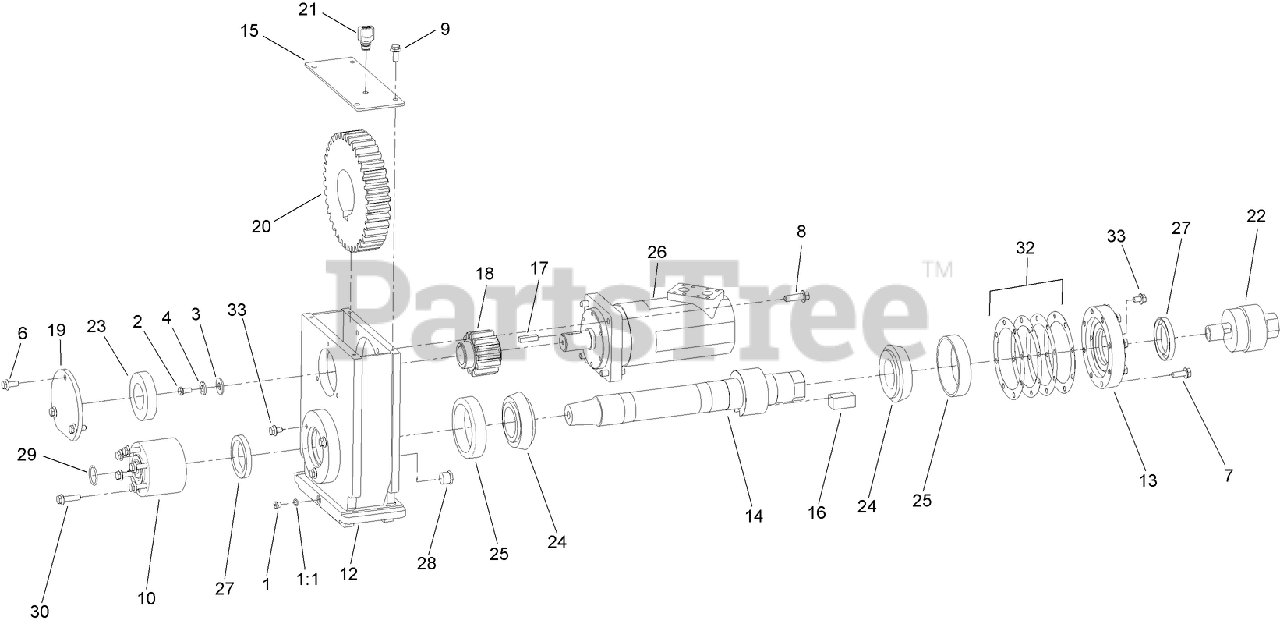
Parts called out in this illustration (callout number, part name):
1	PLUG ASM
1:1	O-RING
2	SCREW-HH
3	WASHER-FLAT
4	WASHER-FLAT
6	SCREW-HHF
7	SCREW-HHF
8	SCREW-HHF
9	SCREW-HHF
10	ADAPTER-SPINDLE
12	BOX-ROTARY
13	PLATE-BEARING CAP
14	SPINDLE-ROTARY
15	ROTARY BOX COVER BLACK]
16	KEY-ROTARY BOX
17	KEY-BOX, ROTARY
18	GEAR-PINION, ROTARY BOX (13T)
19	PLATE-RETAINING, ROTARY BOX
20	GEAR-RING, ROTARY BOX (38T)
21	BREATHER
22	SWIVEL-MUD
23	BEARING-RADIAL BALL
24	CONE-BEARING
25	CUP-BEARING
26	HYD MOTOR ASM
27	SEAL-SHAFT
28	PLUG-SITE, GLASS
29	O-RING
30	SCREW-HHF
32	SHIM-ROTARY BEARING (.001 THICK)
32	SHIM-ROTARY BEARING (.003 THICK)
32	SHIM-ROTARY BEARING (.005 THICK)
32	SHIM-ROTARY BEARING (.010 THICK)
33	SCREW-HHF
